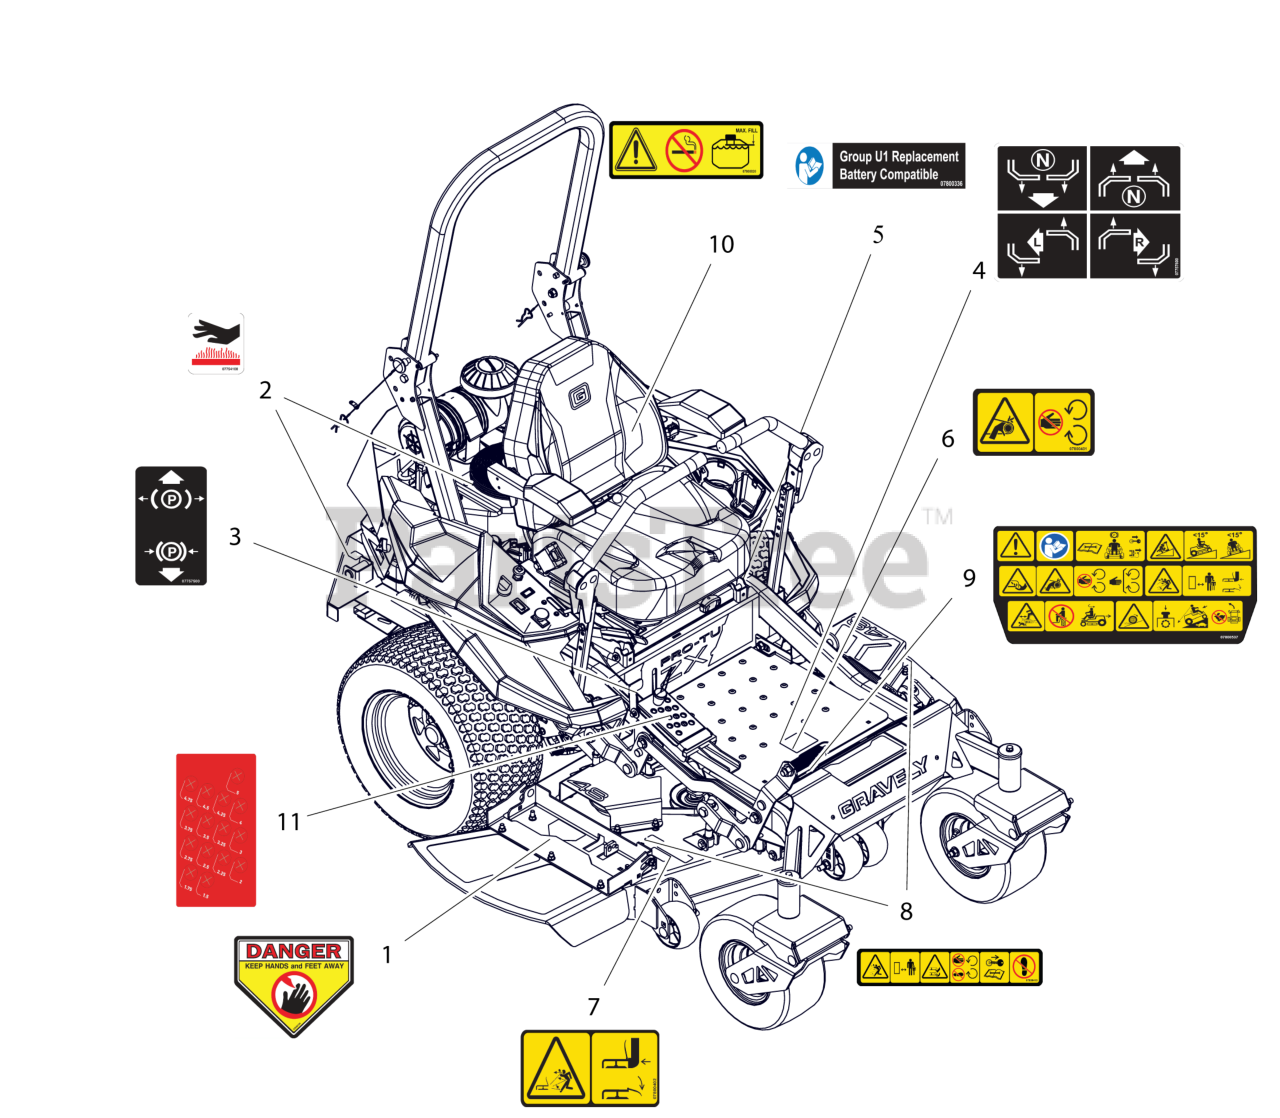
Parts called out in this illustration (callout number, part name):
1	DECAL, DANGER
2	DECAL, HOT SURFACE
3	DECAL, PARKING BRAKE LEVER
4	DECAL, INSTRUCTIONAL-STEERING
5	DECAL, U1 BATTERY REPLACEMENT
6	DECAL, SAFETY - GUARDING
7	DECAL, SAFETY - DECK GUARDING
8	DECAL, DECK SAFETY
9	DECAL, MAIN SAFETY
10	DECAL, FUEL WARNING
11	DECAL, HEIGHT OF CUT
